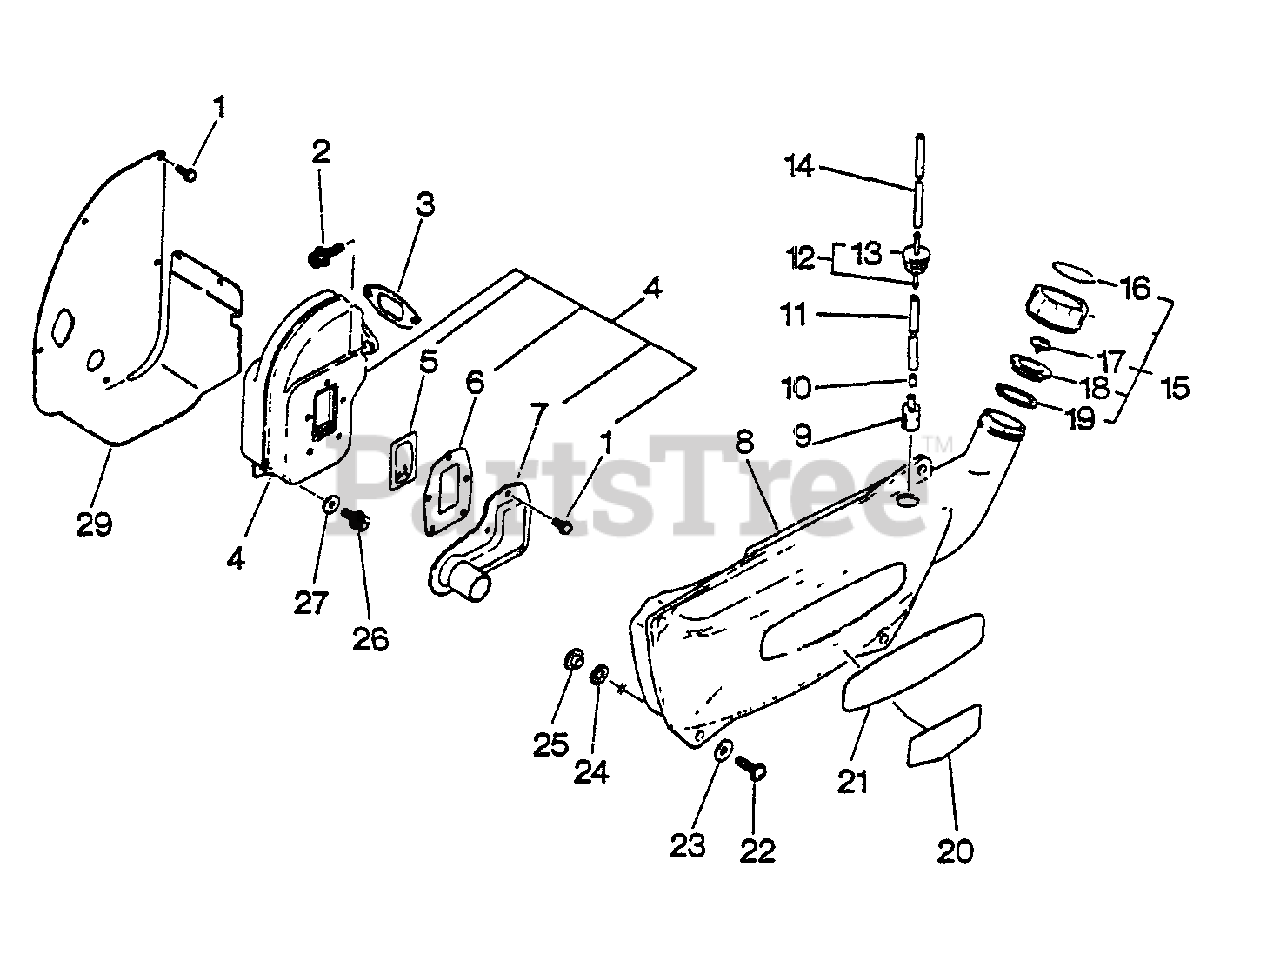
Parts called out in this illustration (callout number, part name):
1	SCREW 4×10
2	BOLT 6×20
3	GASKET, MUFFLER
4	MUFFLER ASSY
5	SCREEN, SPARK ARRESTER
6	GASKET, EXHAUST
7	GUIDE, EXHAUST
8	TANK, FUEL
9	FILTER, FUEL
10	VALVE, CHECK
11	PIPE, FUEL
12	GROMMET KIT
14	PIPE, FUEL
15	CAP ASSY
16	LABEL - FUEL MIX
17	VENT ASSY
18	HOLDER, CHECK VALVE
19	GASKET, FUEL CAP
20	LABEL, MODEL
21	LABEL - ECHO
22	SCREW 5×20
23	WASHER 5.5×18×1
26	BOLT 5×14
27	WASHER 5.2×16×1.0
28	INSULATOR
